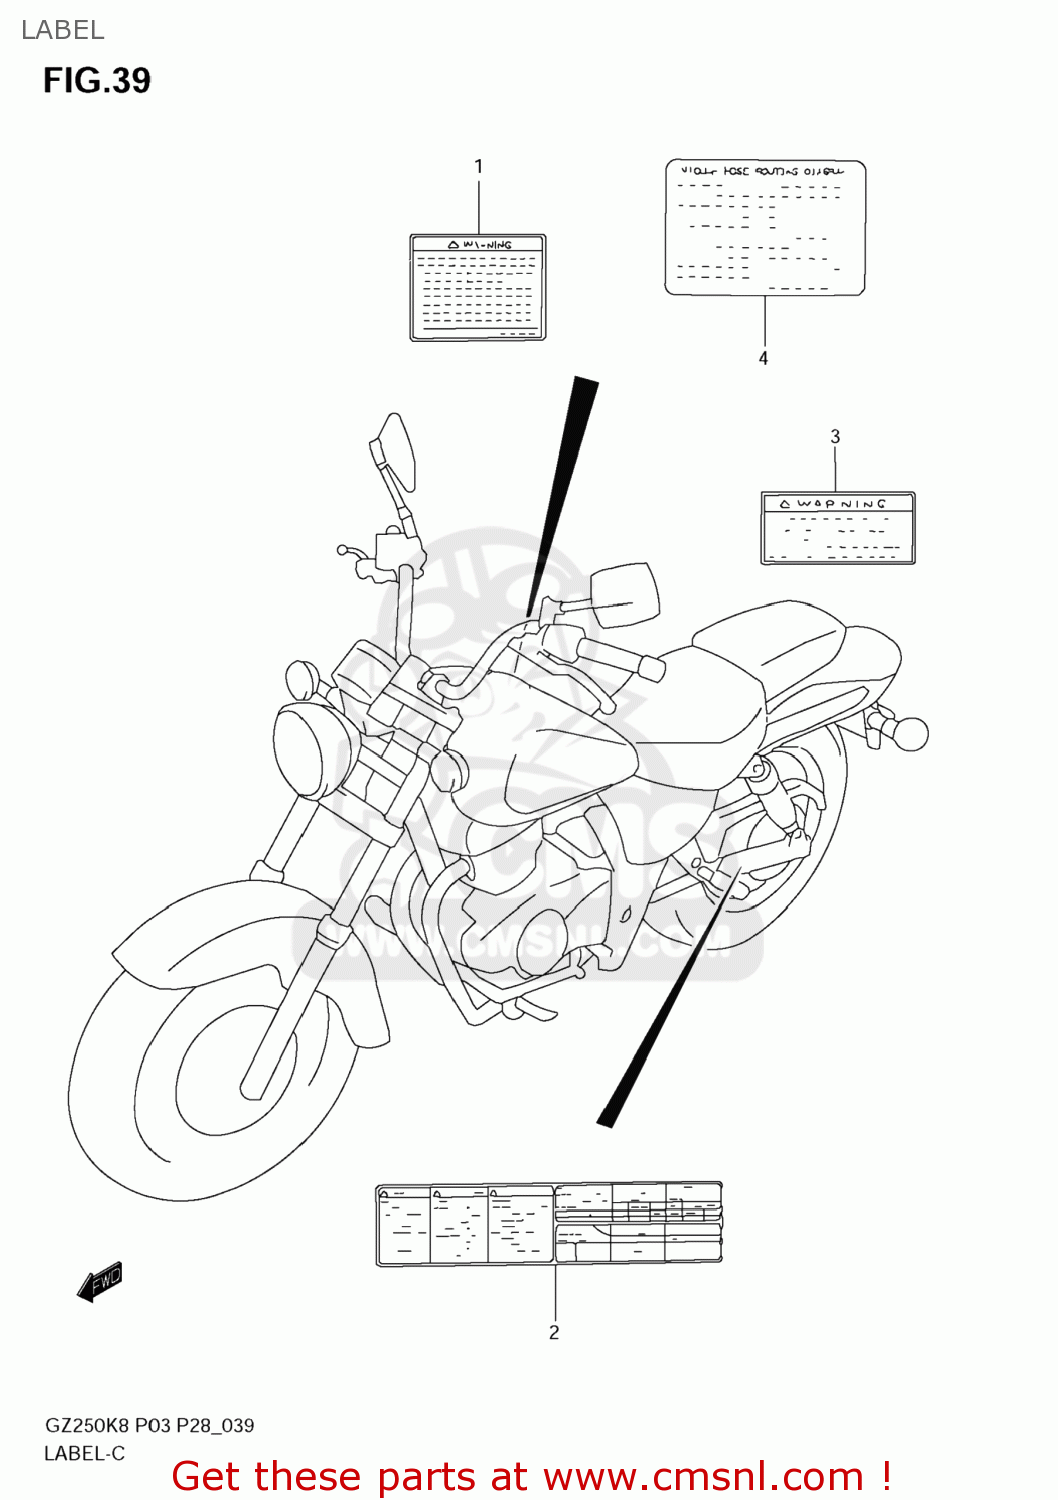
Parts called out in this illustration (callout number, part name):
1	LABEL,GENERAL WARNING
2	LABEL, TIRE INFORMATION
3	LABEL,MANUAL NOTICE
4	LABEL,VACUUM HOSE ROUTING
5	O/M GZ250 2009
